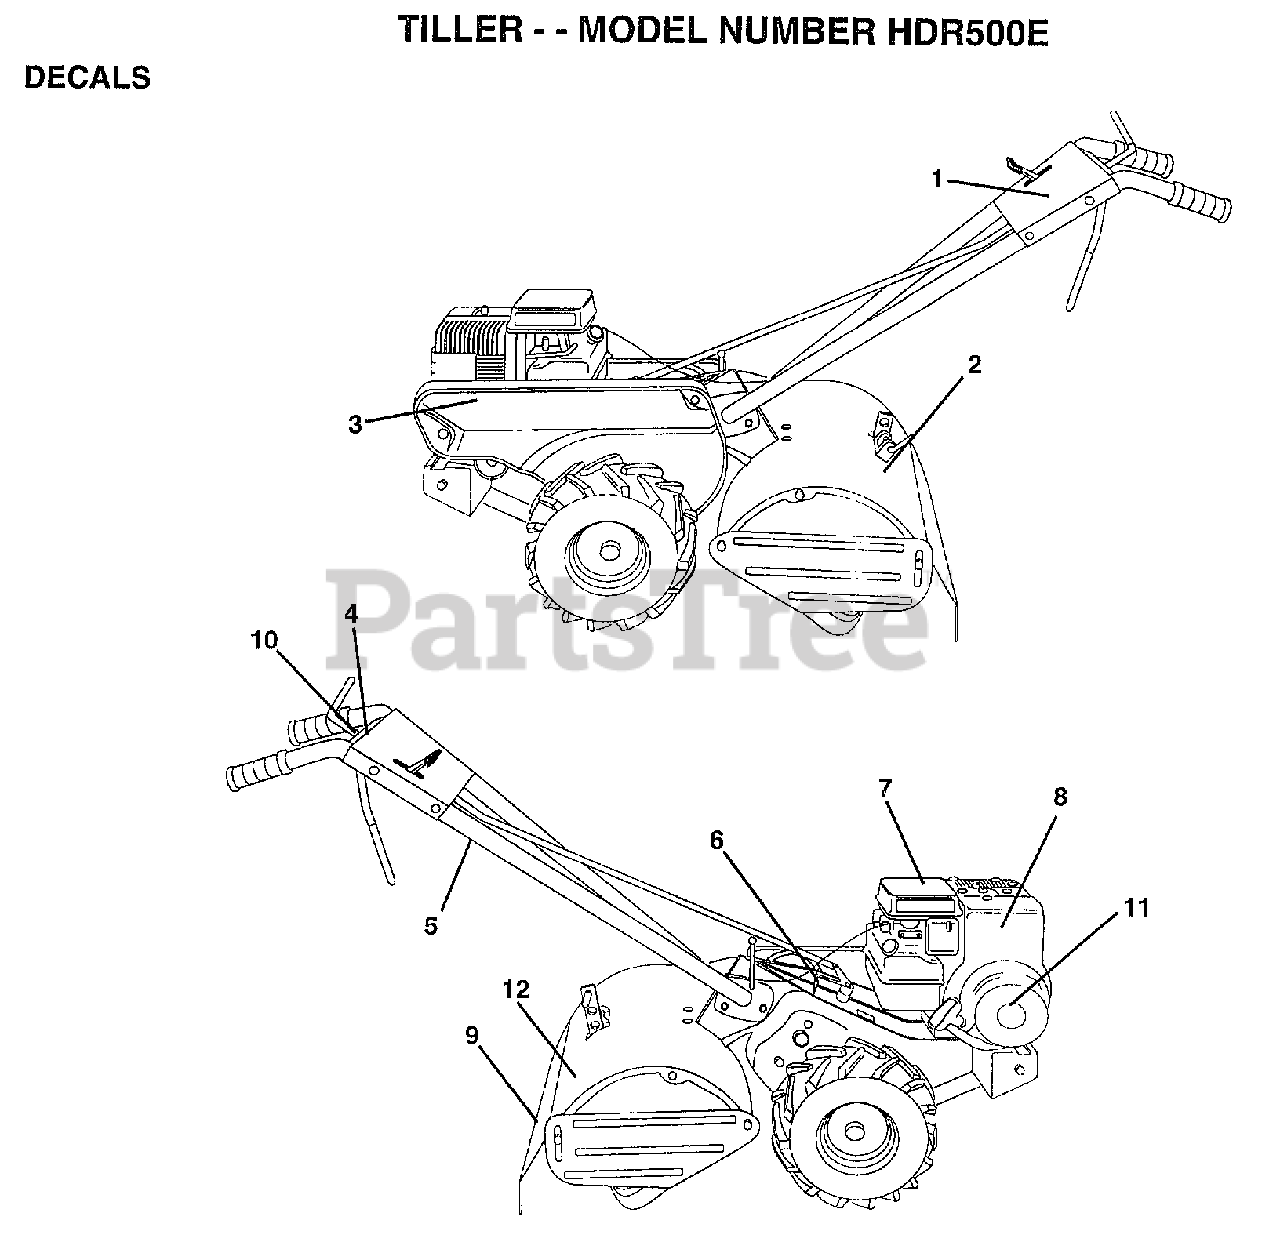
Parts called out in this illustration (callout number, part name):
1	"DECAL PANEL,CTRL"
2	"DECAL SHIELD,TINE"
3	"DECAL GUARD, BELT"
4	DECAL.CONTROL
5	DECAL.HAND.PLACE
6	DECAL CRT
7	DECAL.CAUTION.E/S
8	DECAL, BRIGGS & STRATTON
9	DECAL.WARN.ROT.TI
10	DECAL REVERSE
12	DECAL.TINE.SHIELD
